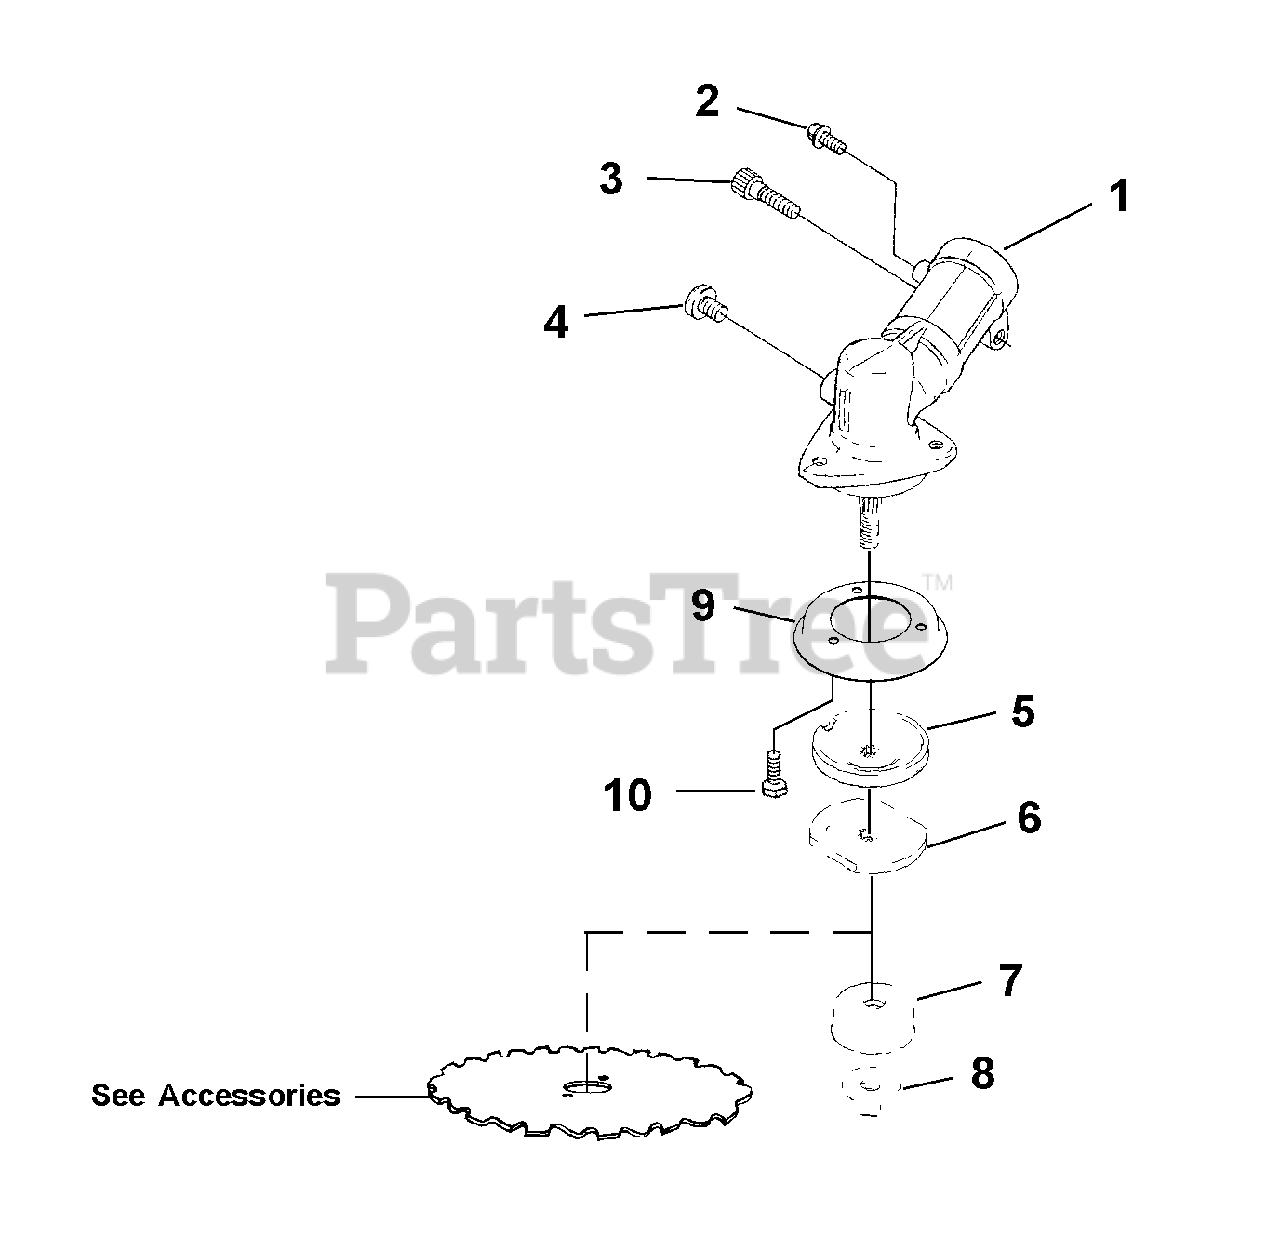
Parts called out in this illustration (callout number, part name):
1	Gear Head
2	Screw
3	Screw, Cap
4	Screw, Grease
5	Washer, Flange (Upper)
6	Washer, Flange (Lower)
7	Nut Guard
8	Nut, Gear Head
9	Anti-Wrap Grass Cover
10	Screw, Cover
